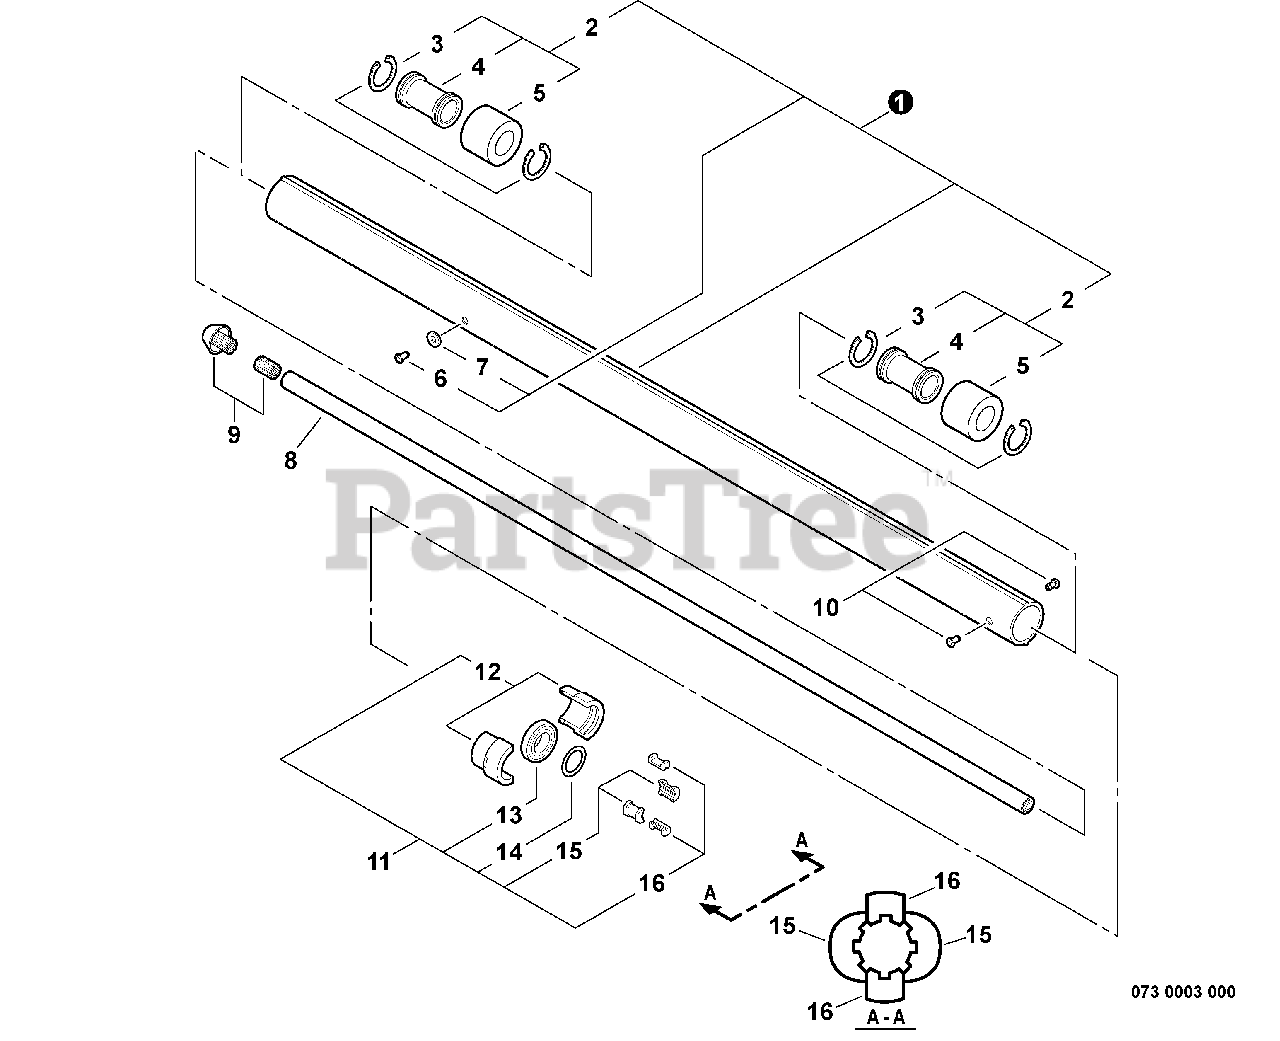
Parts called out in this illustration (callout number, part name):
1	PIPE, MAIN - BLACK
2	DRIVESHAFT GUIDE ASSY
3	RING, RETAINING
4	GUIDE, SHAFT
5	PAD, FOAM
7	WASHER, FLAT 5
8	SHAFT, UPPER DRIVE L= 79.75
9	ADAPTER, UPPER DRIVE SHAFT
11	HOLDER ASSY, BEARING
12	HOLDER, BEARING
13	BEARING, BALL 6002 DDU
14	WASHER, WAVE
15	GUIDE, SHAFT - LARGE
16	GUIDE, SHAFT - SMALL
